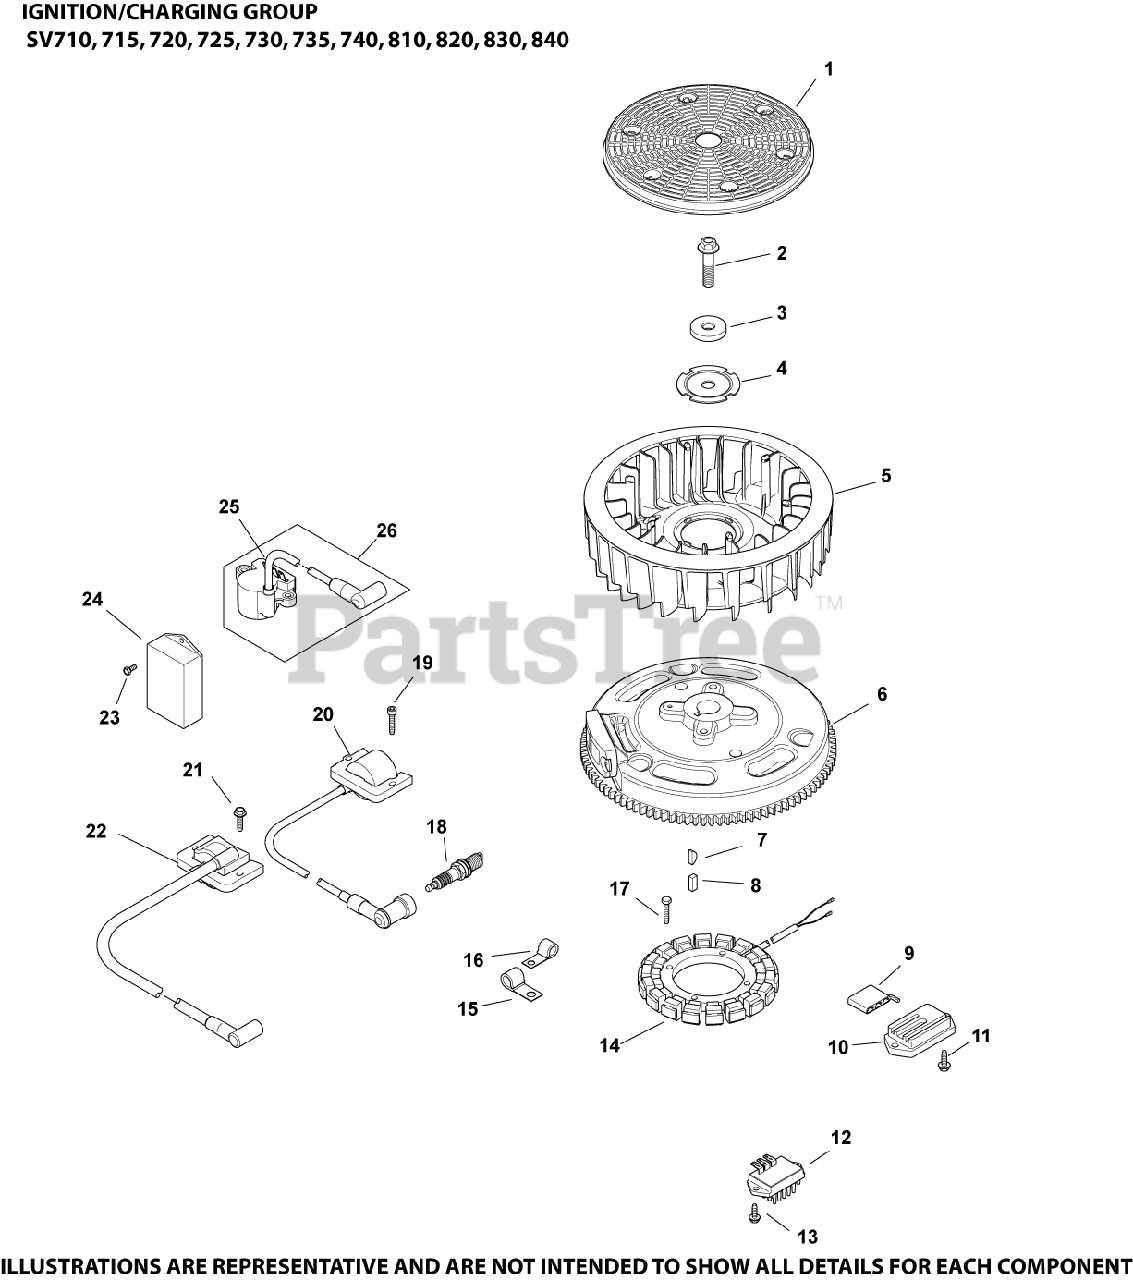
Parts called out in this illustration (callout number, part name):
1	SCREEN, GRASS
2	SCREW, FLG M10X1.5X45 - (#25086361S)
3	WASHER, FLAT 13/32"
4	PLATE, FAN MOUNTING
6	FLYWHEEL ASSEMBLY - USE 32 025 22-S
7	KEY, 3/16" X 5/8"
9	CONNECTOR
10	REGULATOR/RECTIFIER
11	SCREW,FLG THD FRM M5X0.8X16-(#25086398S)
14	KIT, 15 / 20 AMP STATOR
17	SCREW - USE M-548025-S
18	PLUG, SPARK (STD)
21	SCREW, FLG THD FRM M5X.8X20-(#25086399S)
22	KIT, MODULE IGNTN (CDI FIXED)
